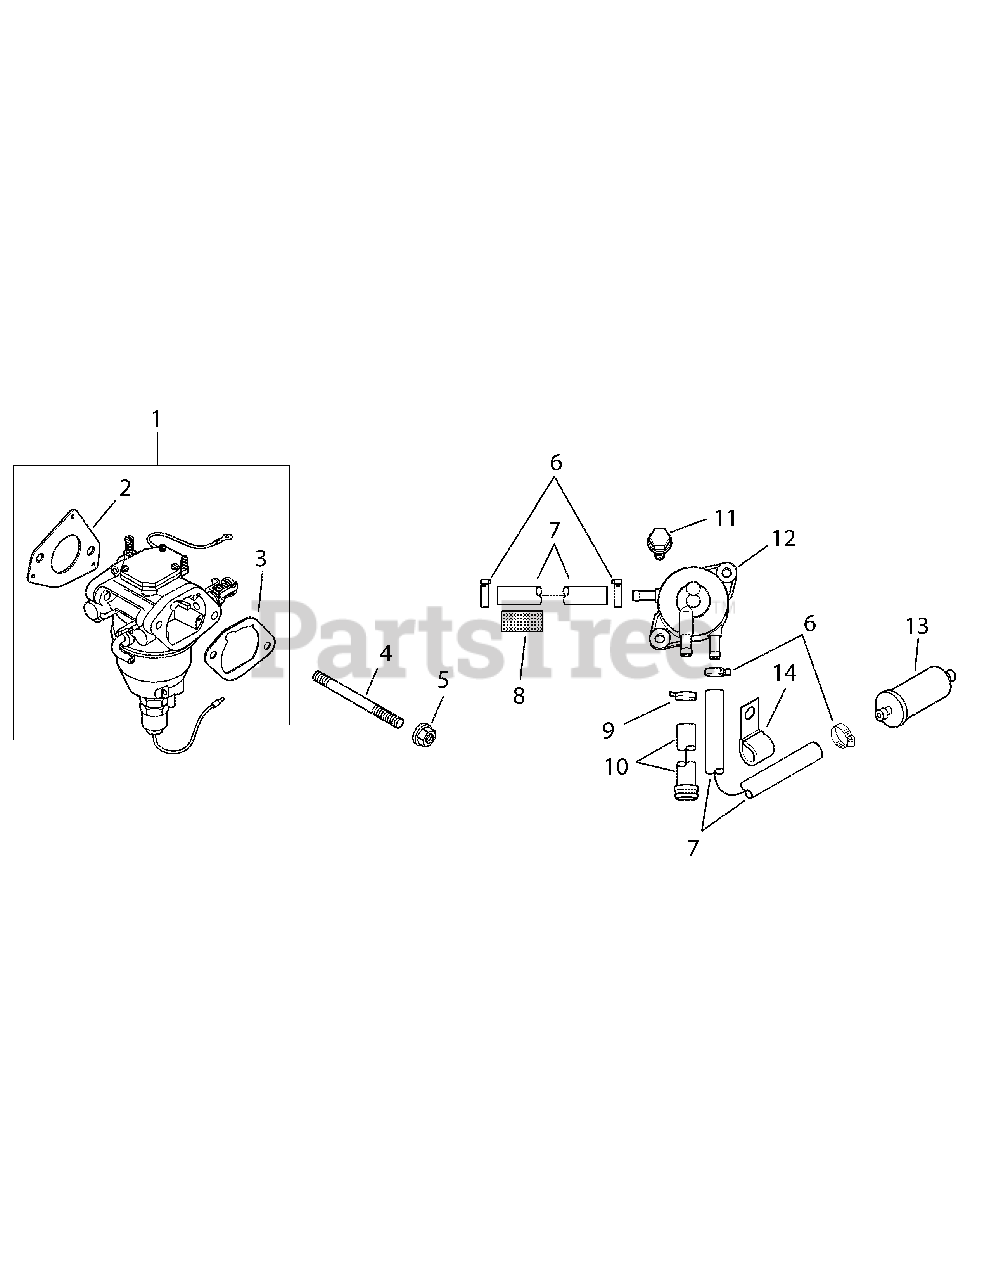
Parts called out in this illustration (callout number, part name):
1	Kit, carburetor w/gaskets
2	Gasket, carburetor
3	Gasket, air cleaner base
4	Stud, carburetor
5	Nut, hex. flange M6x1.0
6	Clamp, hose
7	Line, fuel
8	Sleeve, Anti Abrasion
10	Hose, fuel pump
11	Screw, hex. cap M6x1.7x18
12	Pump, pulse fuel
13	Filter, fuel
